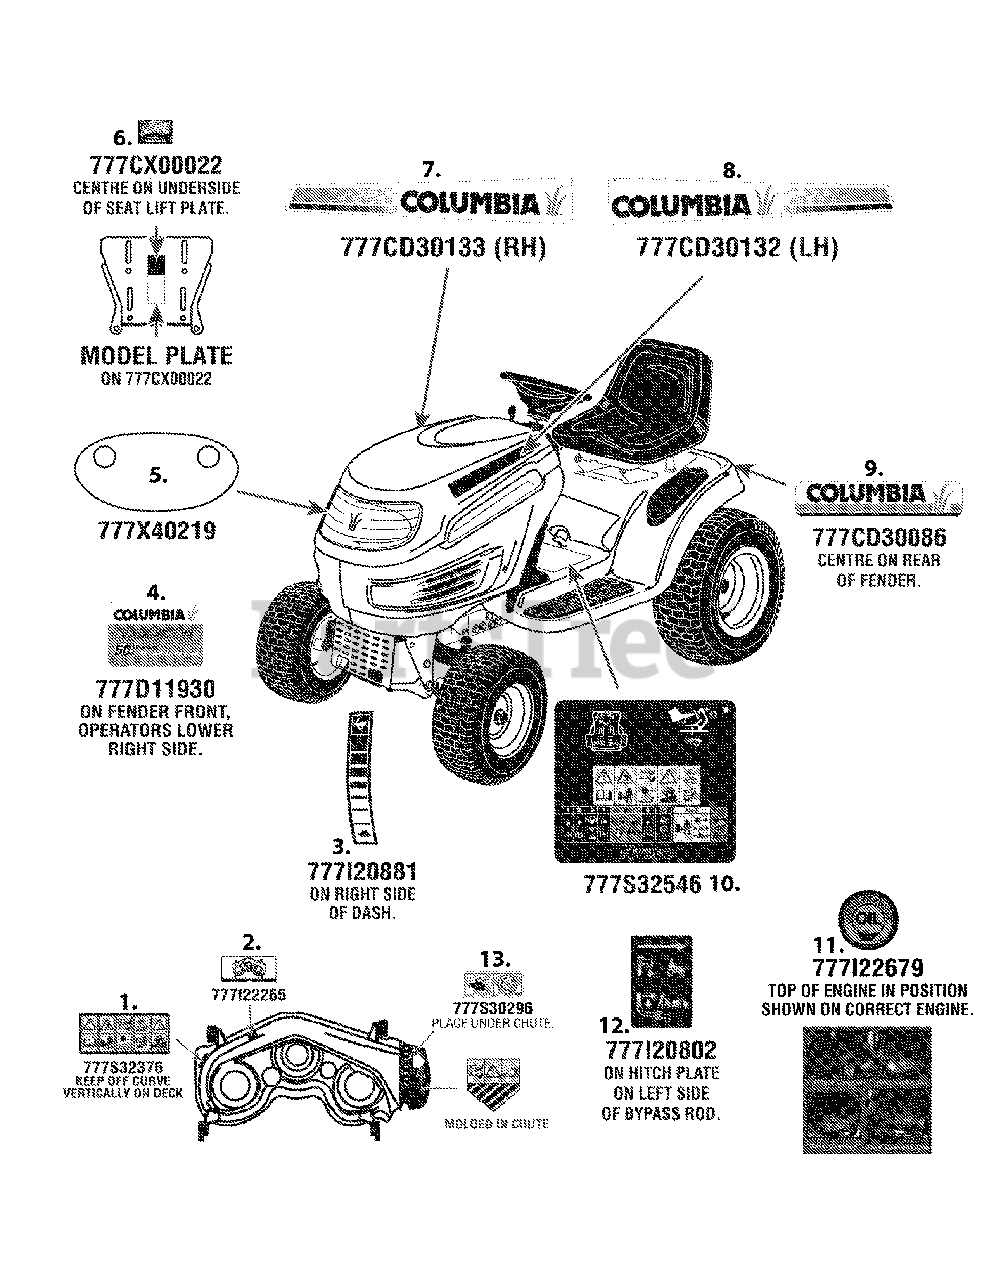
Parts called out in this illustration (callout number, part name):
1	LABEL:RIDER:SAFETY DECK
2	LABEL-BELT ROUTE
4	LABEL-HYD 50" FNDR
5	LABEL-LENS REFLECT
6	LABEL:: MADE IN USA
7	LABEL-HOODSIDE RH
8	LABEL-HOODSIDE LH STY 6
9	LABEL-REAR FENDER
10	LABEL-SAFETY/INST CANADA
11	LABEL-CHECK ENG OIL
12	LABEL-RT-99 HTCHPLT
13	LABEL:RIDER DECK
